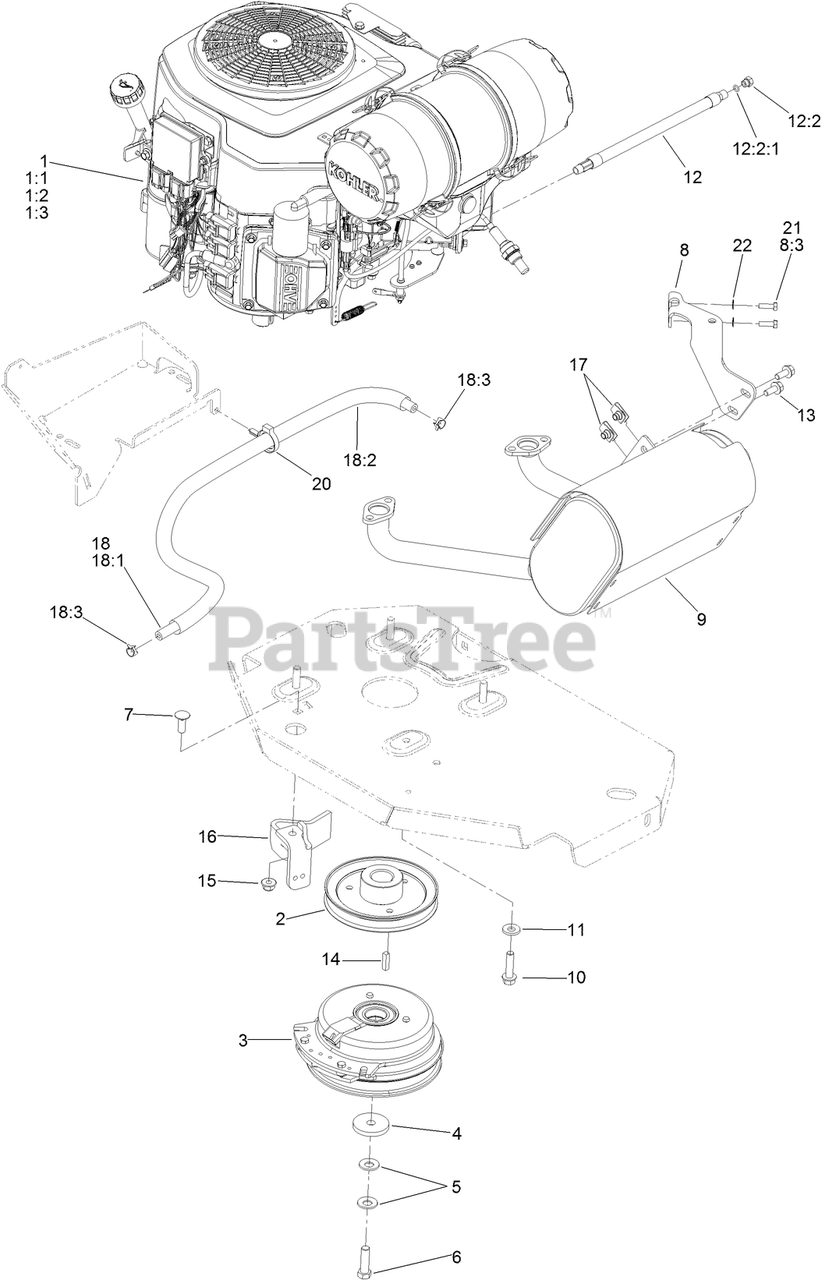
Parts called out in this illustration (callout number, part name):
1:1	KOHLER 52 050 02-S ENGINE OIL FILTER
1:2	KOHLER 25 083 01-S ENGINE AIR FILTER
1:3	KOHLER 25 083 04-S SAFETY FILTER
2	SHEAVE
3	CLUTCH KIT
4	WASHER-CLUTCH
5	WASHER-SPRING
6	SCREW-HH
7	SCREW-CARR
8	BRACKET-MUFFLER
8	MUFFLER BRACKET KIT
8:3	SCREW-HH
9	MUFFLER--KIT
10	SCREW-HWH
11	WASHER-BELLEVILLE
12	OIL DRAIN HOSE ASM
12:2	PLUG-HH
12:2:1	O-RING
13	SCREW-HHF
15	NUT-HF, NI
16	CLUTCH-ANCHOR
17	NUT-U
18	FUEL LINE ASM
18:1	HOSE-FUEL
18:2	SLEEVE-THERMAL
18:3	CLAMP-HOSE
20	CLAMP-HOSE
21	SCREW-HH
22	WASHER-SPRING
